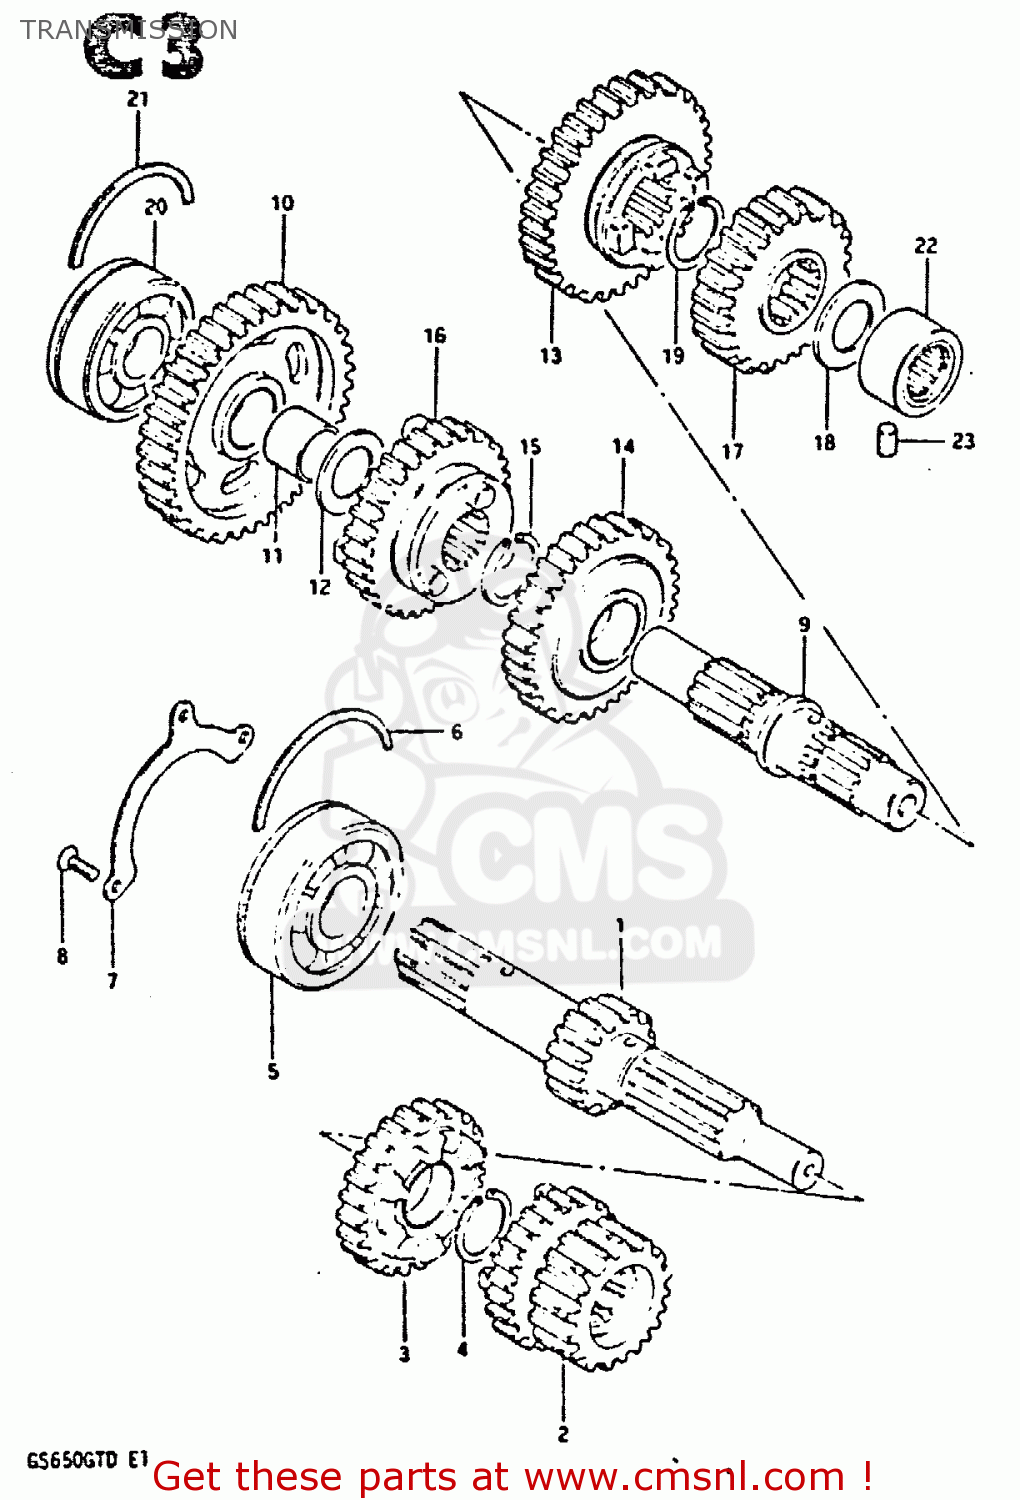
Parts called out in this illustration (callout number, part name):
1	SHAFT,COUNTER
2	GEAR,2ND & 3RD DRIVE
3	GEAR,FOURTH DRIVE
4	CIRCLIP
5	BEARING(25X62X17)
6	C-RING
7	RETAINER,CNTR SHAFT BEARING
8	SCREW
9	SHAFT,DRIVE
10	GEAR,FIRST DRIVEN
11	BUSHING
12	WASHER
13	GEAR,SECOND DRIVEN
14	GEAR,THIRD DRIVEN
15	CIRCLIP
16	GEAR,FOURTH DRIVEN
17	GEAR,REDUCTION(NT:24)
18	THRUST WASHER,REDUCTION
19	CIRCLIP
20	BALL BEARING 20X47X14
21	C RING
22	BEARING(20X34X16)
23	PIN
